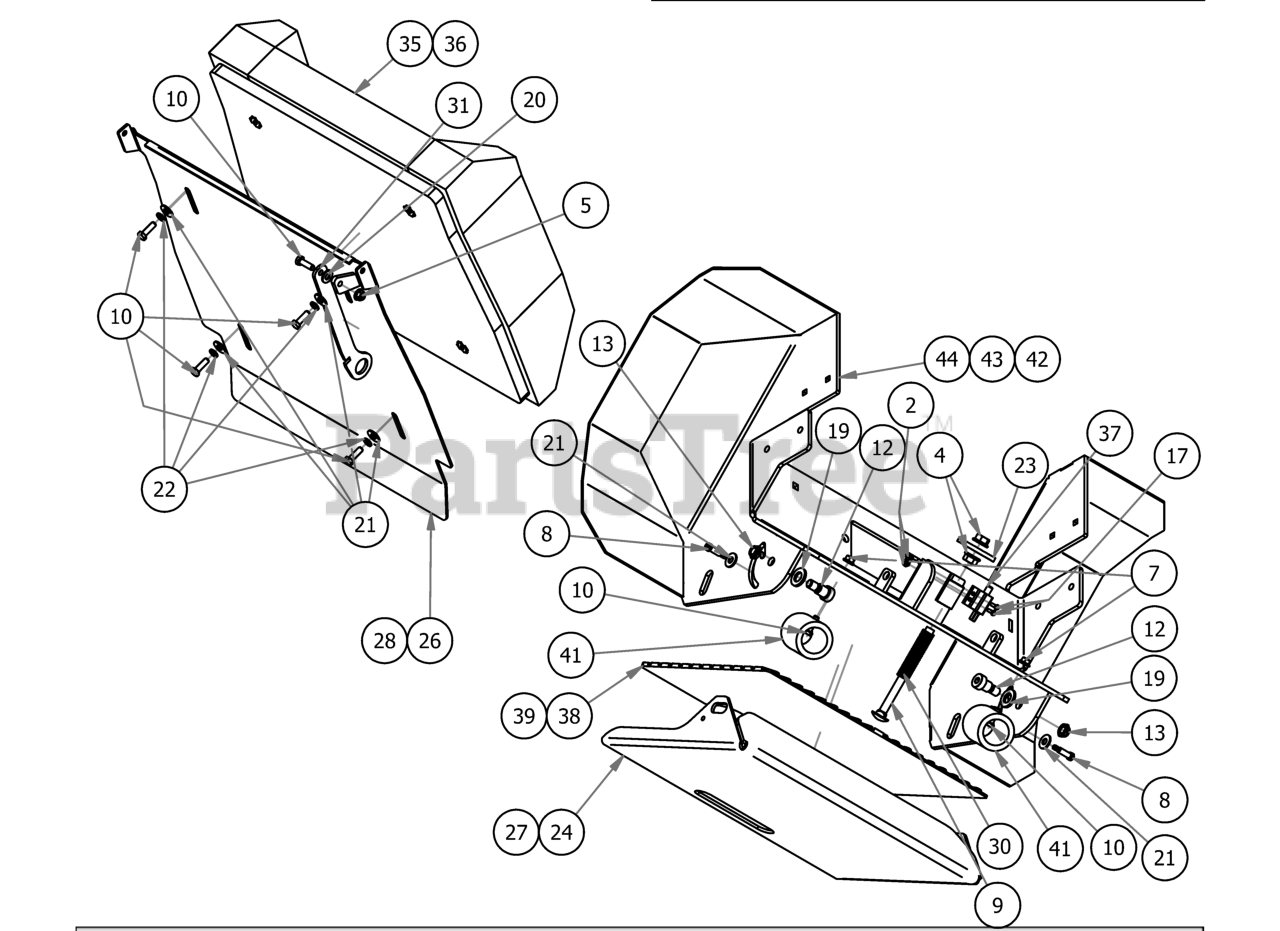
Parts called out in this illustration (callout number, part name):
1	3326 Wellnut (1/4-20 x 5/18")
2	10-24 Nylon Insert Locknut Zin
3	3/8 Nylock Flange Nut
4	1/2" Flange Nut
5	5/16-18 Nylon Flange Nut
6	1/4-20 Nylon Insert Locknut Zi
7	5/16-18 Hex Flange Nuts Zinc w
8	5/16" x 7/8" Socket Head Shoulder Bolt
9	1/2-13 x 6 Carriage Bolt, Grade 2
10	5/16-18 X 1 GR 5 Hex Bolt Zinc
11	3/8"-16 x 2" Gr 5 Hex Bolt
12	5/8'' x 5/8'' Shoulder Bolt
13	1/2-13 NYLON INSERT JAM LOCKNUT ZINC
14	5/16" x 1 1/4" Carriage Bolt
15	3/8" x 1 1/4" Hex Bolt
16	3/8-16 X 1-1/4 Carriage Bolt
17	10-24 X 5/8 BS C/S 18-8 SS
18	1/4-20 X 3/4 GR 5 Hex Bolts
19	.630 ID Plastic Washer
20	.360 ID Plastic Washer
21	5/16 USS FLAT WASHER (7/8 OD) ZINC
22	5/16 SPLIT LOCKWASHER ZINC
23	MZ Deck Idler Spacer
24	2019 Stand-On Platform
25	2019 Stand On Access Panel
26	2019 Stand On Pad Plate Weldment
27	2020 36" Stand-On Platform Plate
28	2020 36 Stand On Pad Plate Weldment
29	1/4"-20 x 3/4" Knurled Thumb Screw
30	Rider Presence Spring 9657K145
31	2019 Stand On Operator Pad Kickstand
32	Outlaw Throttle Cable
33	2019 Stand On Frame Weldment
34	2020 36 Stand On Frame Weldment
35	2019 Stand-On Platform Pad
36	2020 36" Stand-On Platform Pad
37	safety Switch
38	2019 Stand On Mat
39	2020 36 Stand On Mat
40	2019 Revolt Wiring Harness
41	GBR-647 Miner Elastomer
42	Stand On Platform Support_61 weldment
43	2020 36" Stand On Platform Support weldment
44	2019 Stand On Platform Support weldment
